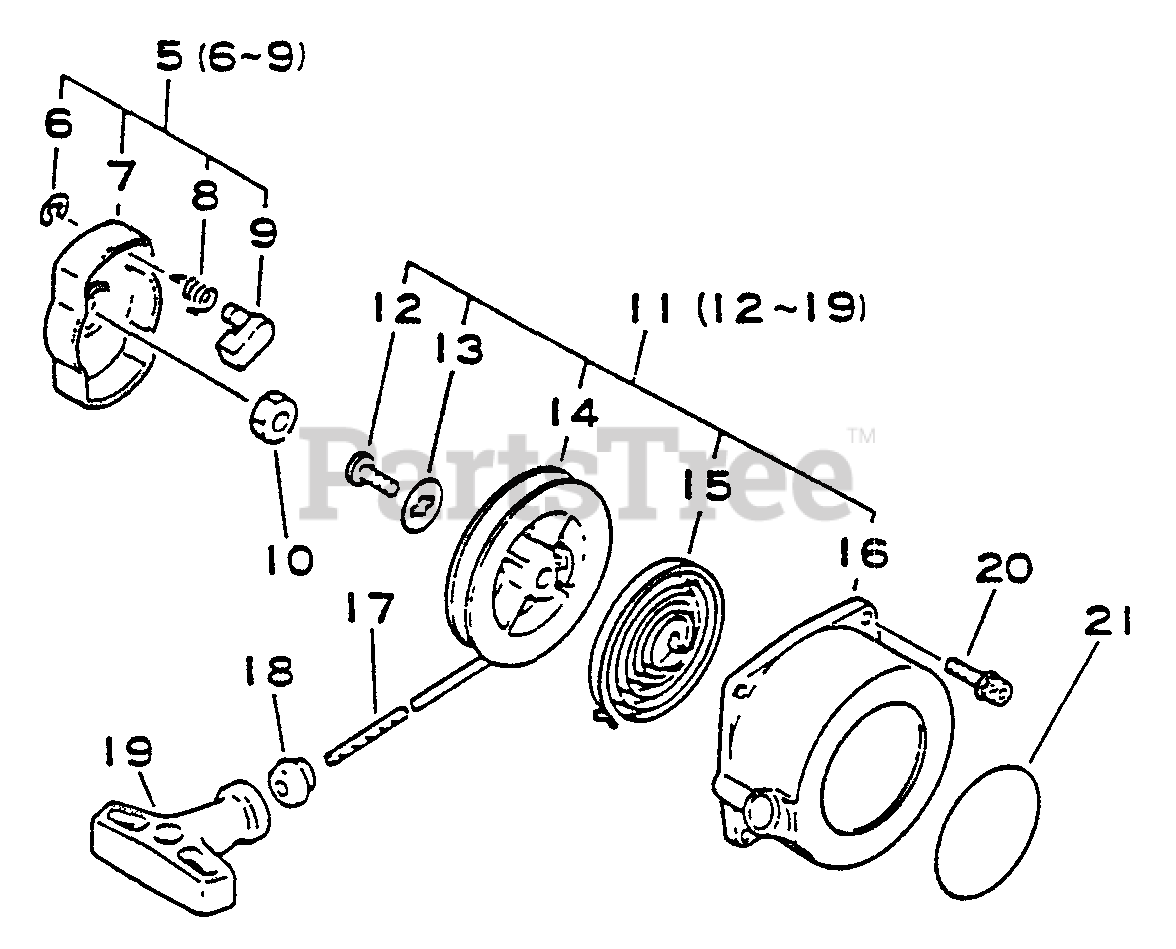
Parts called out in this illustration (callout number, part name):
5	STARTER PAWL ASSY
6	RING, RETAINING - 6
7	CATCHER, PAWL
8	SPRING, RETURN
9	PAWL, STARTER
11	STARTER ASSY
14	REEL, ROPE
15	SPRING, REWIND
16	CASE, STARTER - ORANGE
17	ROPE, STARTER - 4X880
18	GUIDE, ROPE
19	GRIP, STARTER
20	SCREW - 4X20
21	LABEL - ECHO
